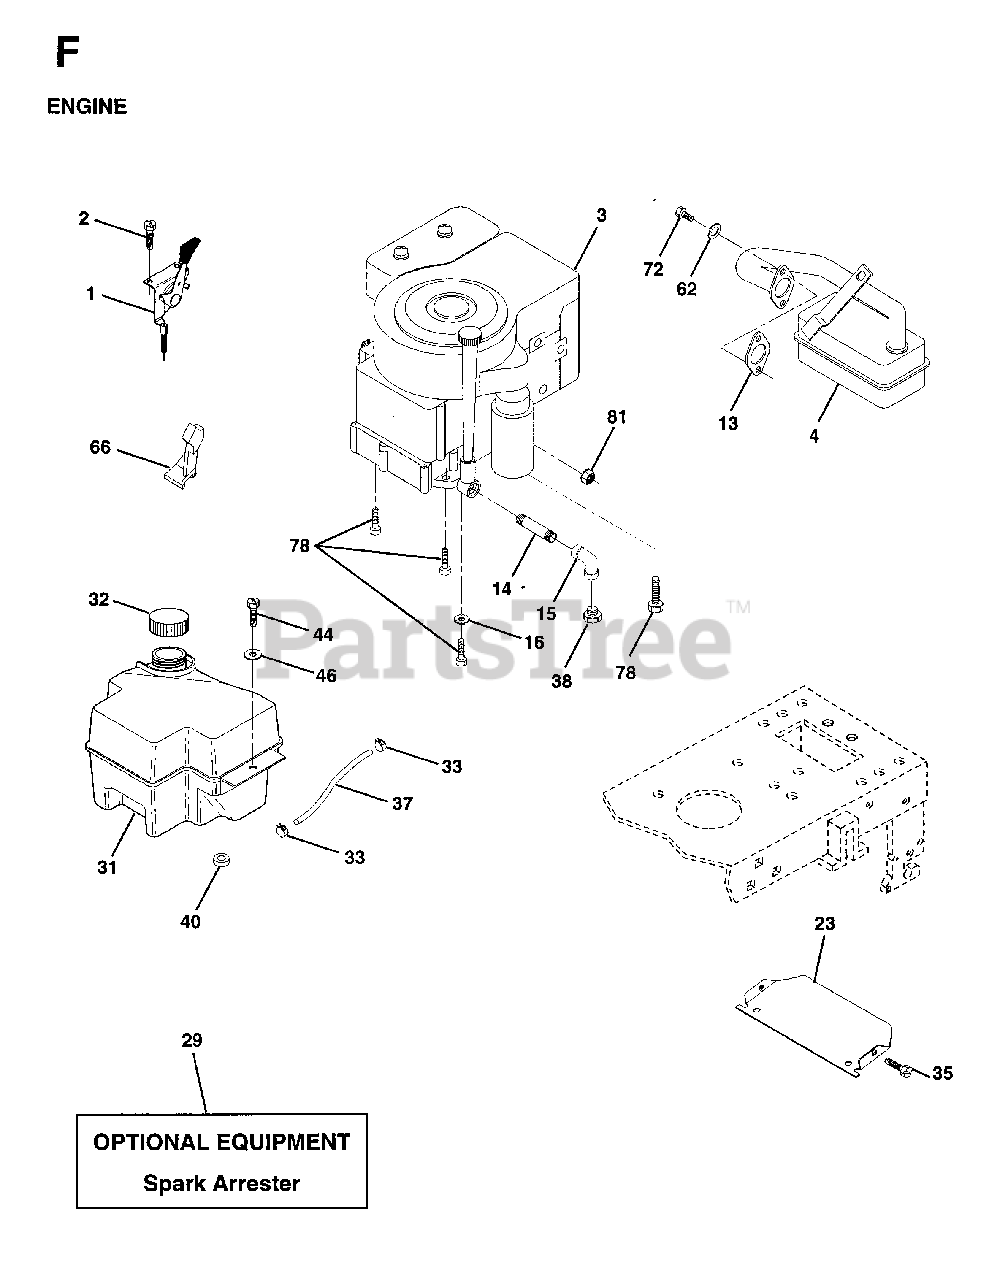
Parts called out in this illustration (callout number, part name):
1	CONTROL
2	SCREW LT
13	GASKET ENG
15	ELBOW
16	LOCKWASHER
23	SHIELD HEAT
29	ARRESTER SPARK (OPTIONAL)
31	FUEL TANK
32	FUEL CAP
33	HOSE CLAMP
35	SCREW
37	LINE.FUEL.20
40	SNAP BUSHING T
44	SCREW HEX CRT
62	LOCKWASHER
66	STOP THROTTLE
72	SCREW
78	SCREW
81	NUT FLANGE 1/4-20 STARTER NUT
